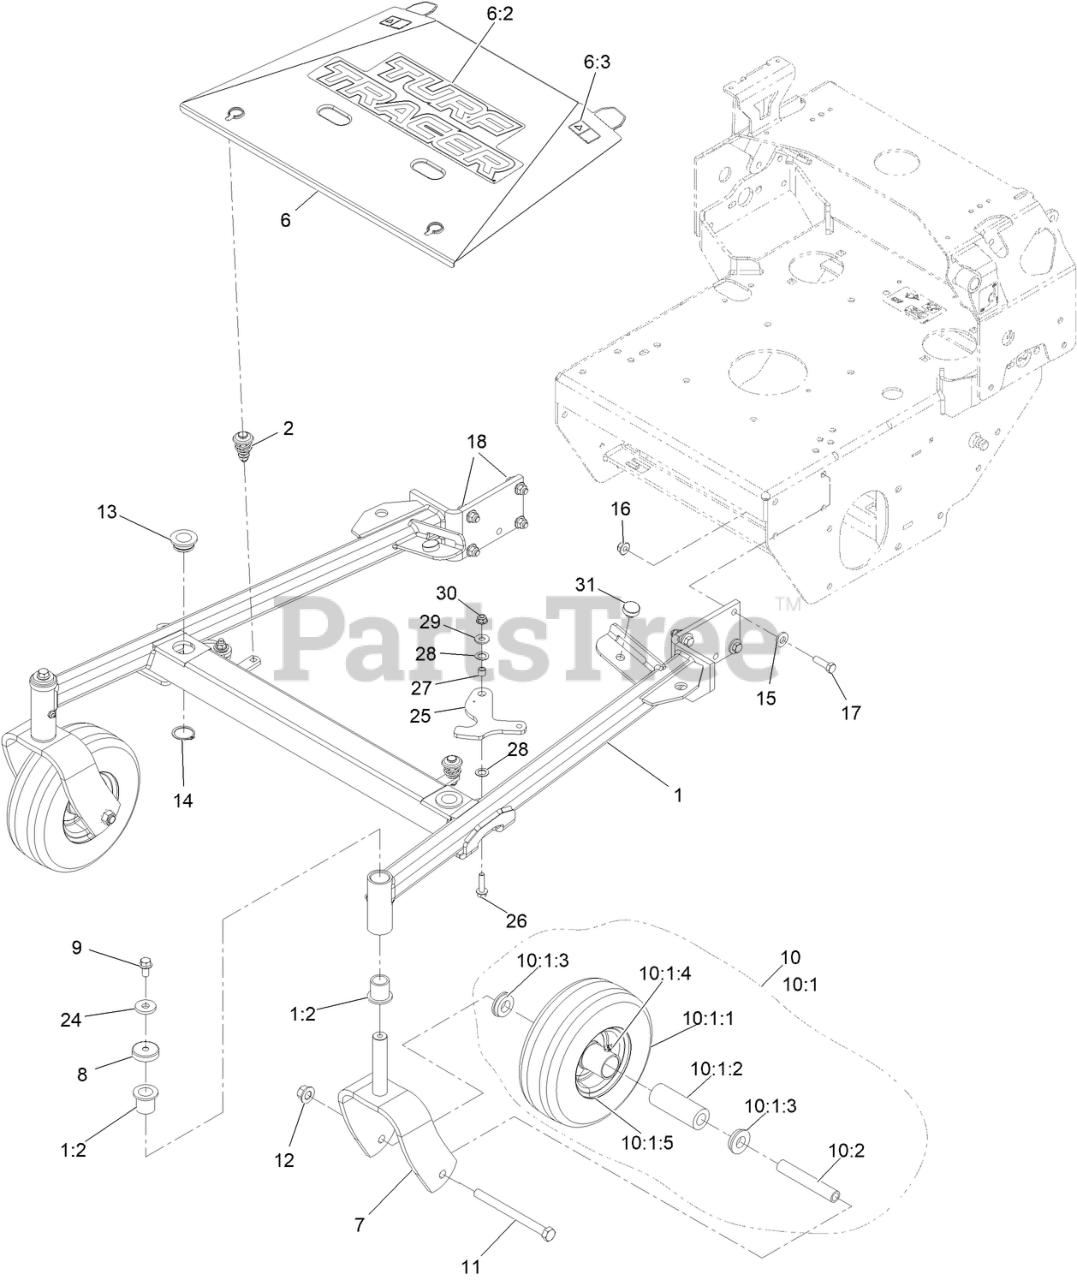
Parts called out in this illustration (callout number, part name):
1	ASM-48" Tts Front Frame
1:2	BEARING-FLANGED
2	HOOD RETAINER, TURF TRACER
6	ASM-48" Tts Center Shield
6:2	DECAL-TURF TRACER
6:3	DECAL-WARNING
7	FORK, CASTER
8	CAP, DUST
9	SCREW-HHF
10	KIT, SP CASTER WHEEL REPLACEMENT
10:1	Wheel And Tire ASM
10:1:1	Tire
10:1:2	BEARING
10:1:3	BUSHING
10:1:4	FITTING-GREASE
10:1:5	Wheel
11	SCREW-HH
12	Nut-Lock 1/2-13
13	BUSHING-DECK
14	RING-RETAINING
15	WASHER-BELLEVILLE
16	NUT-HF, NI
17	SCREW-HH
18	SCREW-HH
25	LATCH, DECK HEIGHT
26	Screw-HHF
27	Spacer-Grommet
28	WASHER-CONICAL
29	WASHER-FLAT
30	NUT-HF, NI
31	BUMPER-RUBBER
